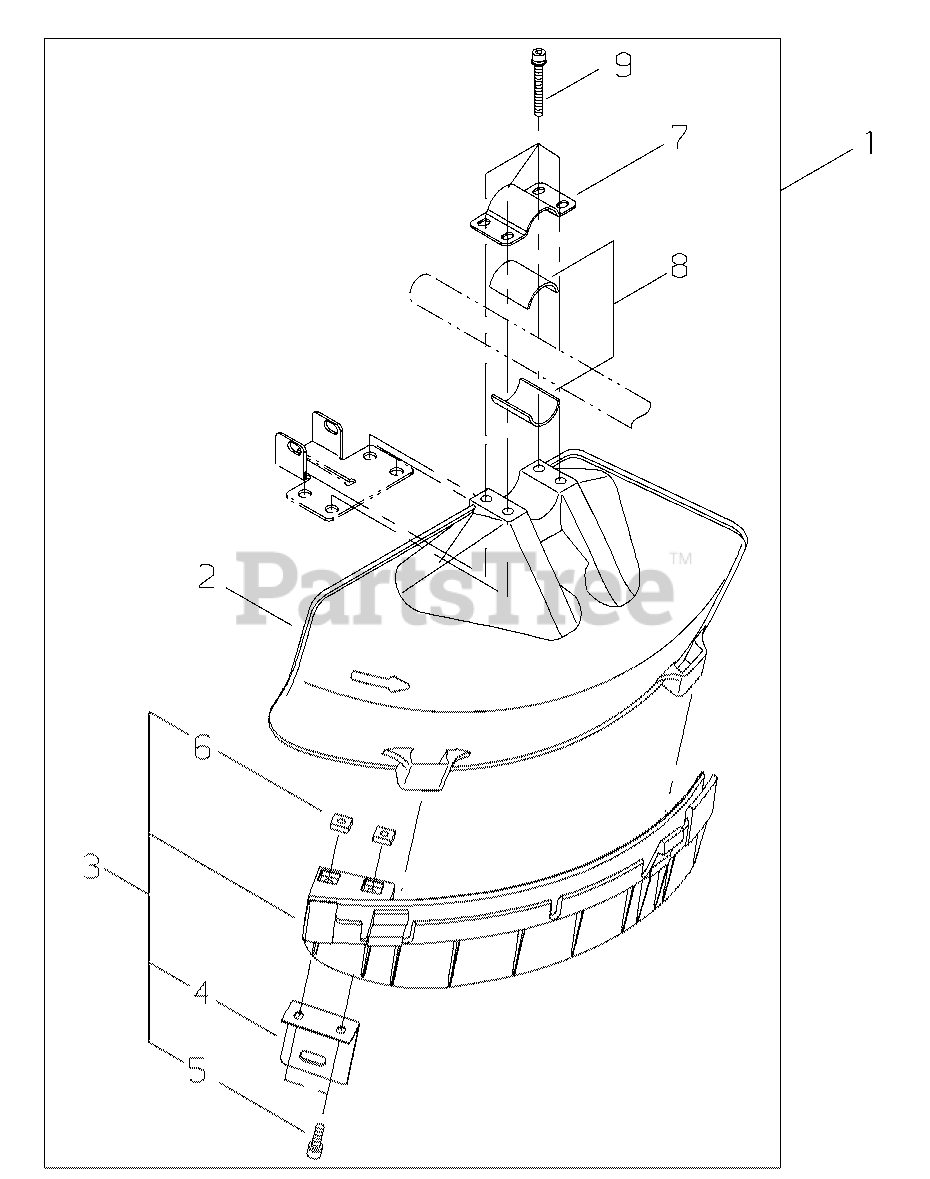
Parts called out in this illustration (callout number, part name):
1	DEBRIS SHIELD KIT
2	SHIELD, DEBRIS
3	SHIELD GUARD KIT
4	KNIFE, TRIMMER LINE
5	SCREW - 5X16
6	NUT - 5
7	CLAMP - UPPER
8	SPACER
9	SCREW - 5X45
